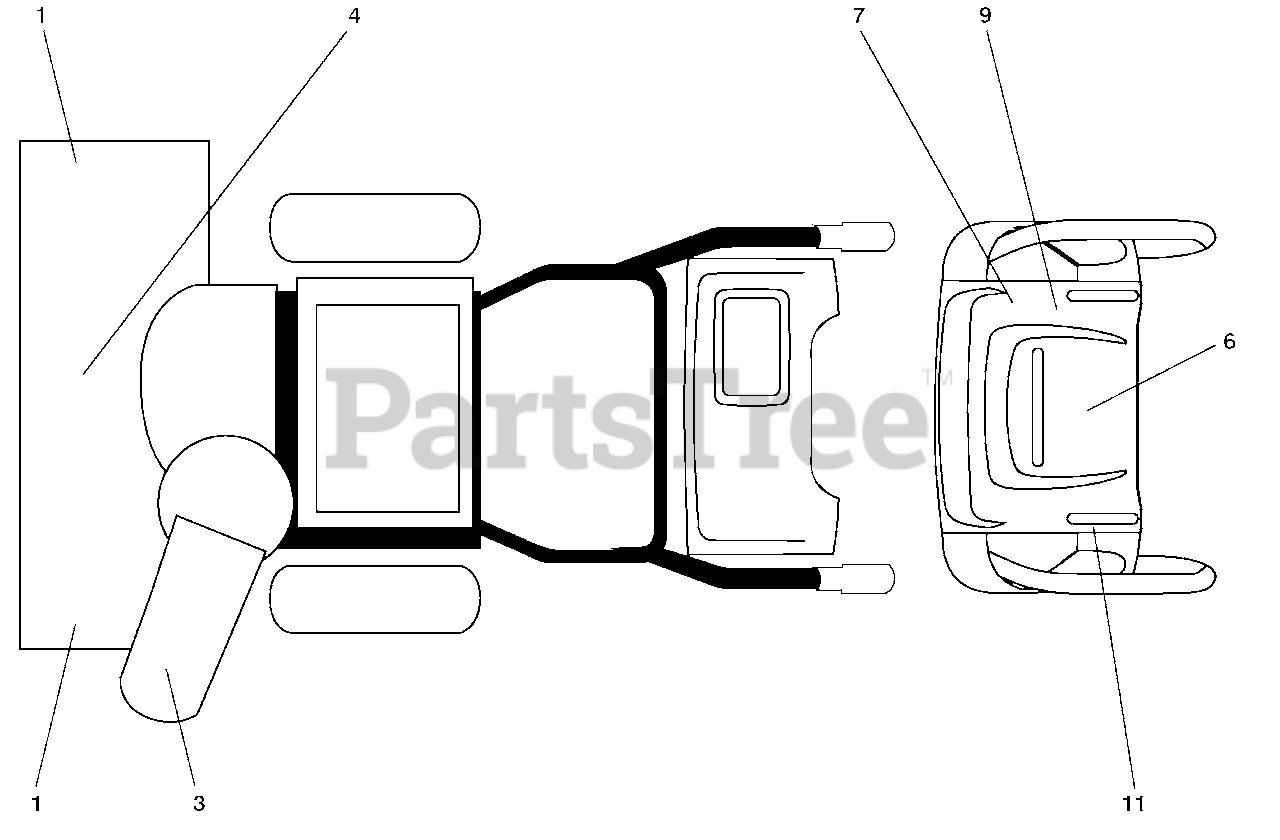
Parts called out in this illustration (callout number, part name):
1	DECAL, DANGER
3	DECAL, DANGER, DEFLECTOR
4	DECAL, DANGER
6	DECAL, INSTRUCTION
7	DECAL, AUGER LEVER RT
9	DECAL, SPEED CONTROL
11	DECAL, TRACT/CLUTCH LEVER
